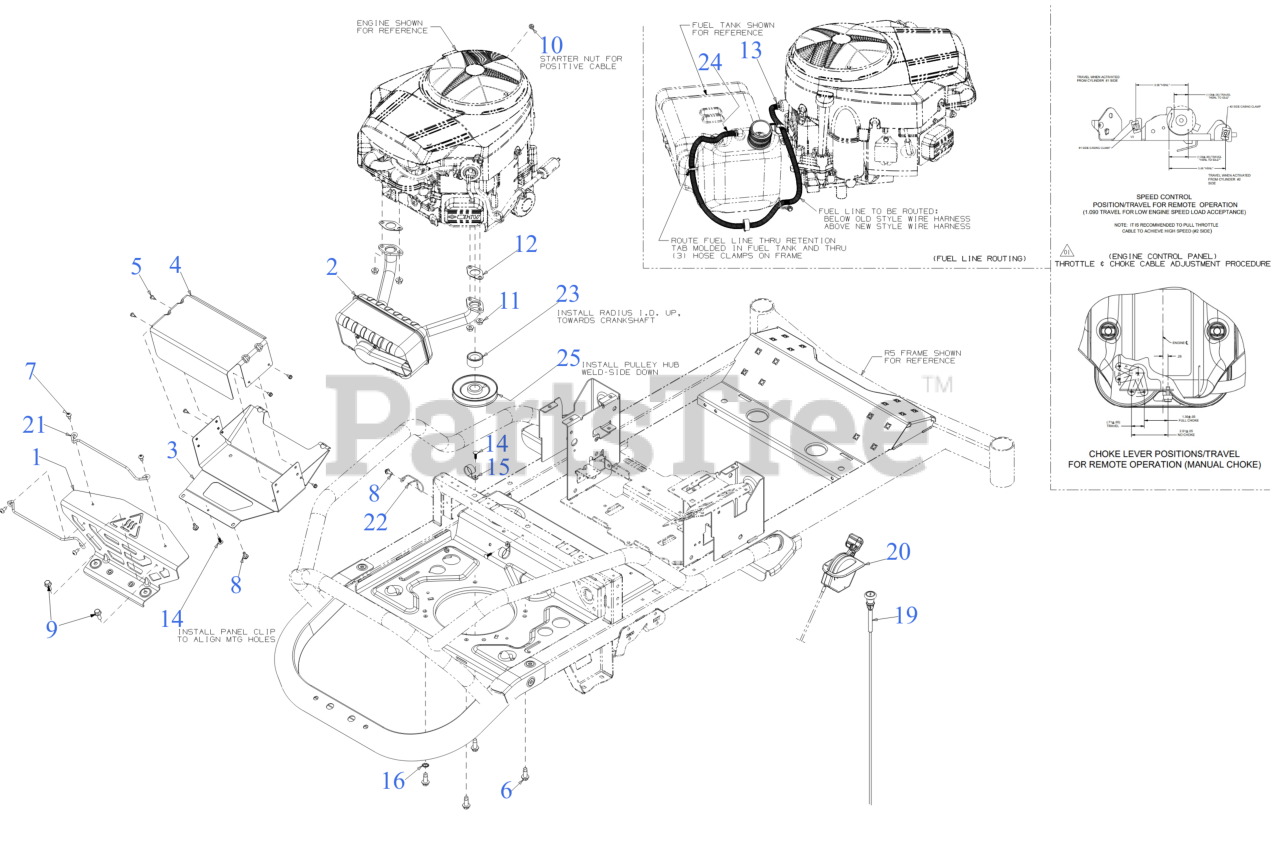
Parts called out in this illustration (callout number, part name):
1	MUFFLER COVER (REAR) (BLACK)
1	NUT RIVET 5/16-18
2	EXHAUST MUFFLER (B&S TWIN)
3	MUFFLER SHIELD (LOWER)
4	MUFFLER SHIELD (TOP)
5	HEX SCREW AB-TAP #10 x .50
6	SCREW 3/8-16 x 1
7	SCREW 1/4-20 x .5
8	SCREW M6-1 x .625
9	SCREW 5/16-18 x .875 GR5 HXFLG HD
10	HEX NUT 1/4-20
11	HEX FLANGE NUT M8X
12	MUFFLER GASKET
13	HOSE CLAMP 1/20
14	RATCHET CLIP (.188 x .85)
15	DRAIN HOSE CLAMP
16	LOCK WASHER 3/8
19	CHOKE CABLE 43.25 LG
20	THROTTLE CABLE 38.0 LG
22	HOSE GUIDE
23	ENGINE PULLEY SPACER
24	FUEL HOSE LOW PERMEATION 36"
25	TRANSMISSION DRIVE PULLEY
